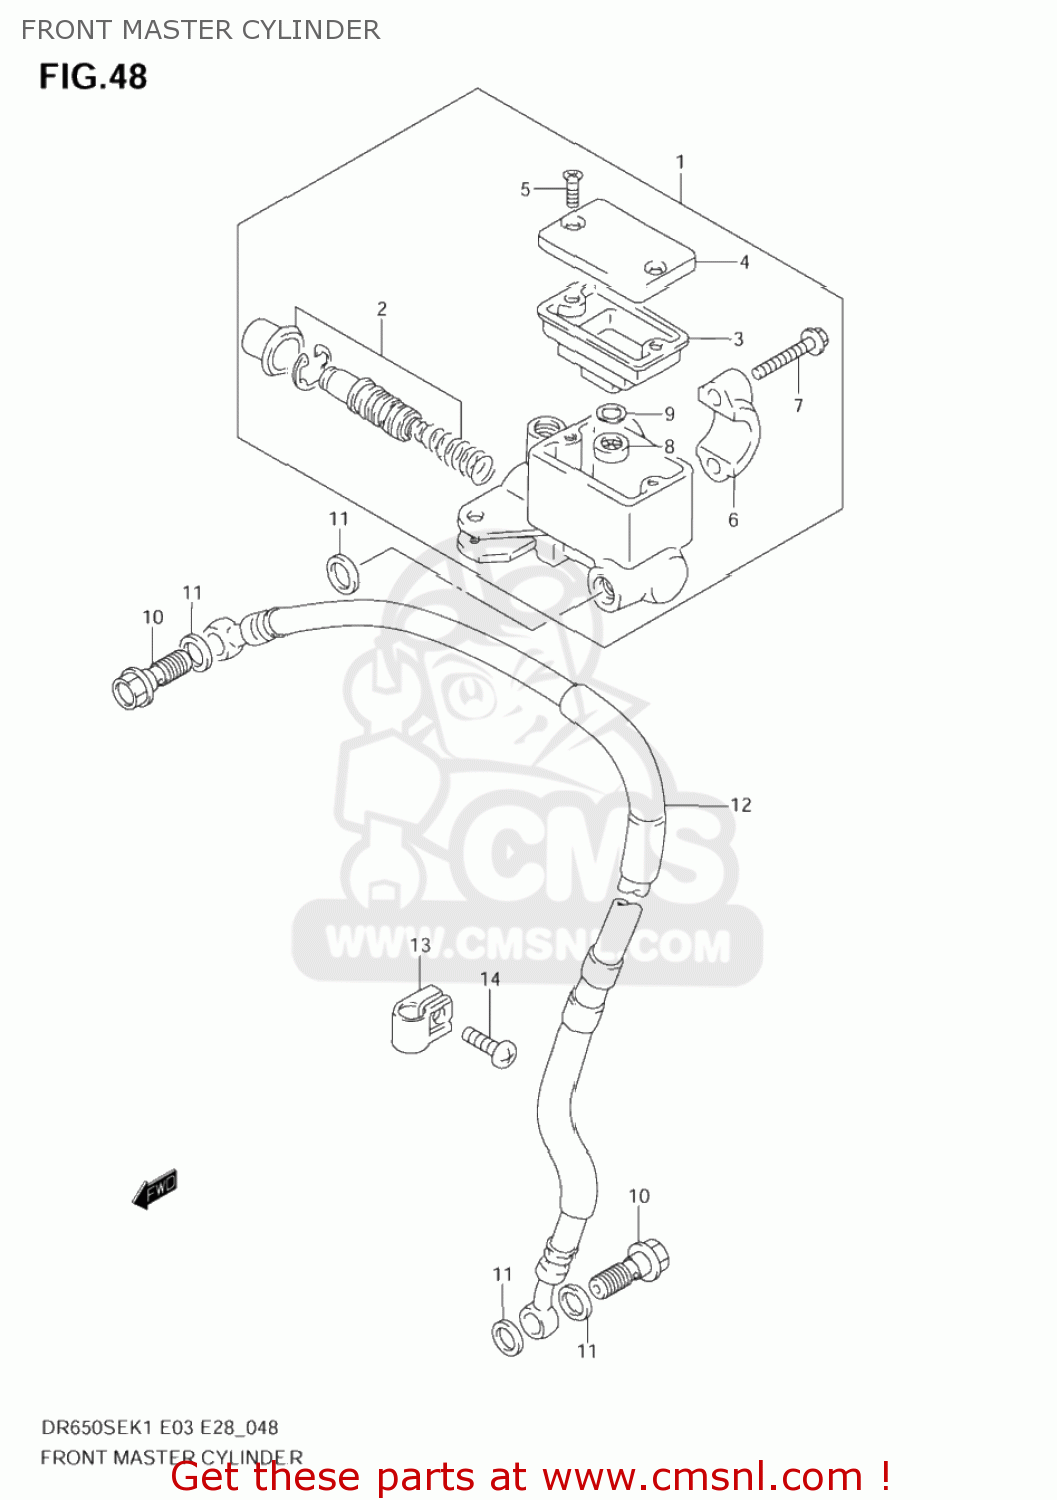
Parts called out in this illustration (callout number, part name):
1	CYLINDER ASSEMBLY,FRONT MASTER
2	PISTON/CUP SET
3	DIAPHRAGM
4	CAP
5	SCREW
6	HOLDER
7	BOLT(6X25)
8	SEPERATOR
9	PLATE
10	BOLT UNION
11	WASHER(10X15X1.5)
12	HOSE COMP,FRONT BRAKE
13	CLAMP,BRAKE HOSE
14	SCREW
